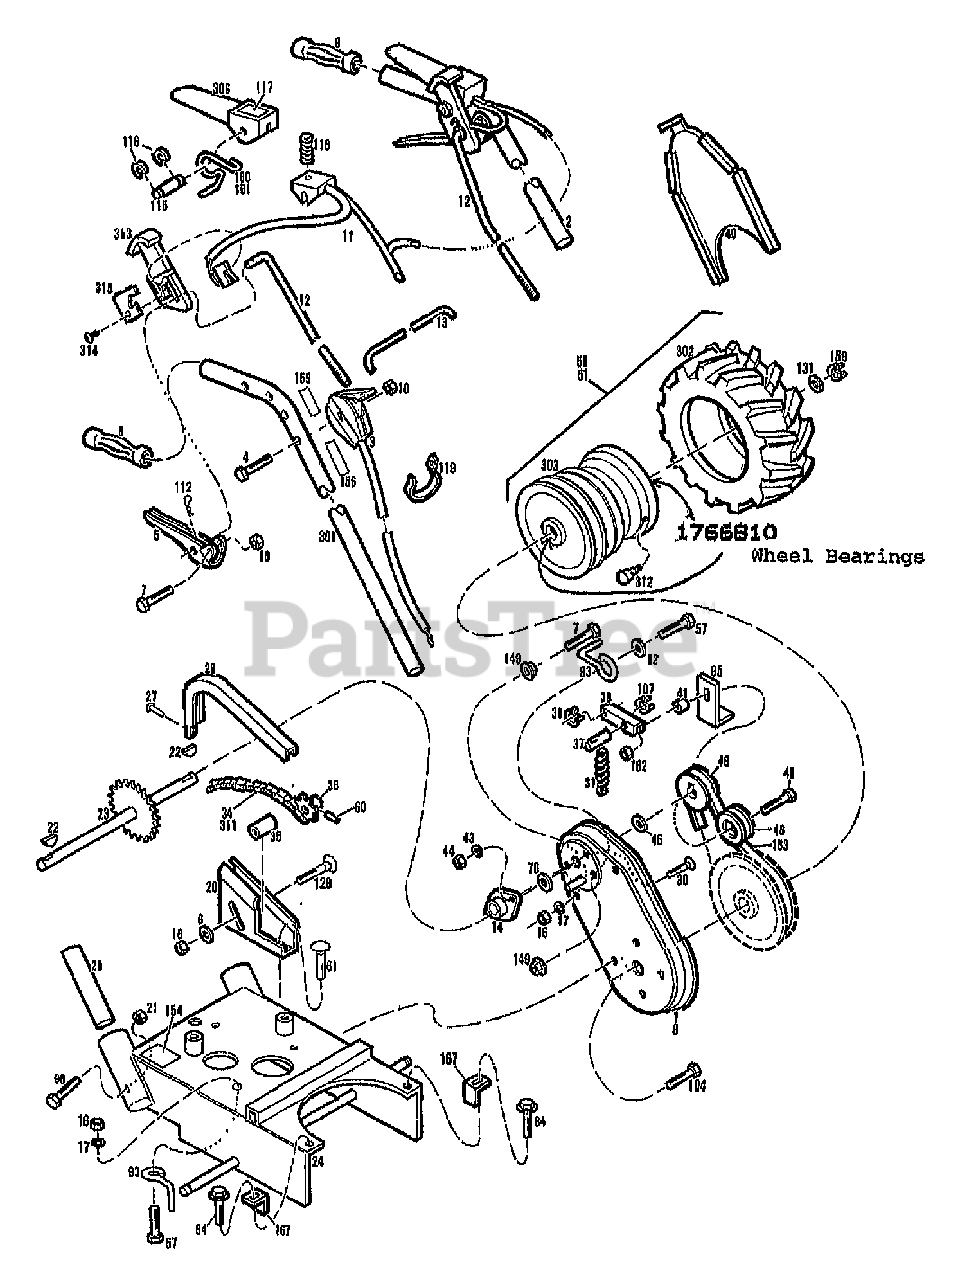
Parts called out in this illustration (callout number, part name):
1	ASSM-BELT GUARD LH
2	HANDLEBAR-LH
3	ASSM-THROTTLE
4	SCR-HH 1/4-20X1.75 G5 ZP
5	LEVER-WHEEL CLUTCH ZP
6	WASHER-FLAT 5/16 SAE
7	SCR-HH 1/4-20X1.5 G5ZP
8	ASSM-BELT GUARD RH
9	GRIP-FLEX
10	NUT-H/LK 1/4-20
11	HARNESS-OPERATOR INTERLK (INCL. 313-315)
12	ROD-WHEEL CLUTCH
13	BRIDGE-HANDLEBAR E-COAT
14	BEARING-FLANGE
16	NUT-HEX 5/16-18 ZP
17	WASHER-LK .312 INT TOOTH
20	ABSORBER-SHOCK
21	NUT-TOP/LK 5/16-18 ZP
22	KEY-WOODRUFF .188X.75
23	ASSM-COUNTER SHAFT-PLATED
24	DECK-ENGINE
26	BRKT-CHAIN IDLER PNT
27	SCR-HW M10-24X.5 STH ZP
29	COVER-CHAIN PNT
30	SCR-CARR 1/4-20X.50
31	CLUTCH-SPRING WHEEL
34	CHAIN W/LINK (INCL. 311)
35	ROLLER-CHAIN IDLER
36	SPROCKET-CHAIN 12T
37	PIVOT-IDLER ARM
38	RING-RET."E" .300 ID
39	ARM-IDLER WHEEL CLUTCH ZP
40	CVR-WHL/BELT GUARD PNT
41	SPACER-WHEEL IDLER
43	WASHER-LK .25 ZP
44	NUT-HEX 1/4-20 ZP
45	SPACER .625 ID
46	SHEAVE-COUNTER SHAFT
48	IDLER-FLAT
49	SCR-HH 3/8-16X2.25 G5 ZP
50	ASSM-WHL&SEAL LH GRAY (INCL. 302, 303, 312)
51	ASSM-WHL&SEAL RH GRAY (INCL. 302, 303, 312)
57	SCR-HHC 5/16-18X.75 GR 5 ZP
60	PIN-ROLL .188X1.0
61	SCR-CARR 5/16-18X.75
70	WASHER-1.0X.64X.029
82	WASHER-FLAT 5/16 SAE
84	SCR-HFLK 5/16-18X.75 ZP
93	GUIDE-BELT
95	GUIDE-BELT WHL CLUTCH
98	SCR-HH 5/16-18X2.25 G5ZP
104	SCR-HFLK 5/16-18X.625 STH
107	RING-RET."E" .437 ID
112	PIN-CLIP .08
115	PIN-PIVOT .25"
116	RING-CRESCENT EXT
117	DECAL-OPC CONTROLS
118	SPRING-COMPRESSION
119	TIE-CABLE NYLON BLACK
128	SCR-CARR 5/16-18X1.25 G2ZP
131	WASHER-1.25X.765X.049
149	NUT-HF/LK 1/4-20 ZP
154	DECAL-OIL DRAIN LOCATION
155	DECAL-THROTTLE {34032/033}
155	DECAL-THROTTLE SETTINGS {34034/035}
156	DECAL-PLACE HAN/PULL ROPE
159	RING-RET."E".577 ID
160	SPRING-CONTROL LH
161	SPRING-CONTROL RH
162	NUT-H/LK 3/8-16
167	GUIDE-BELT
301	HANDLEBAR-RH W/DECAL (INCL. 155 & 156)
302	TIRE-LUG 13X5.00-6
303	ASSM-WHEEL
305	LOCTITE-242 (.5 ML TUBE)
306	LEVER W/DECAL (INCL. 117)
311	LINK-CHAIN CONNECTOR
312	STEM-VALVE
313	KIT-WHEEL CONTROL LK (S/BAR)
314	SCR-PHP M4-24X.31
315	KIT-WHEEL CONTROL LK (S/BAR)
315	PAINT-RED SPRAYCAN POWDER (13OZ. CAN)
